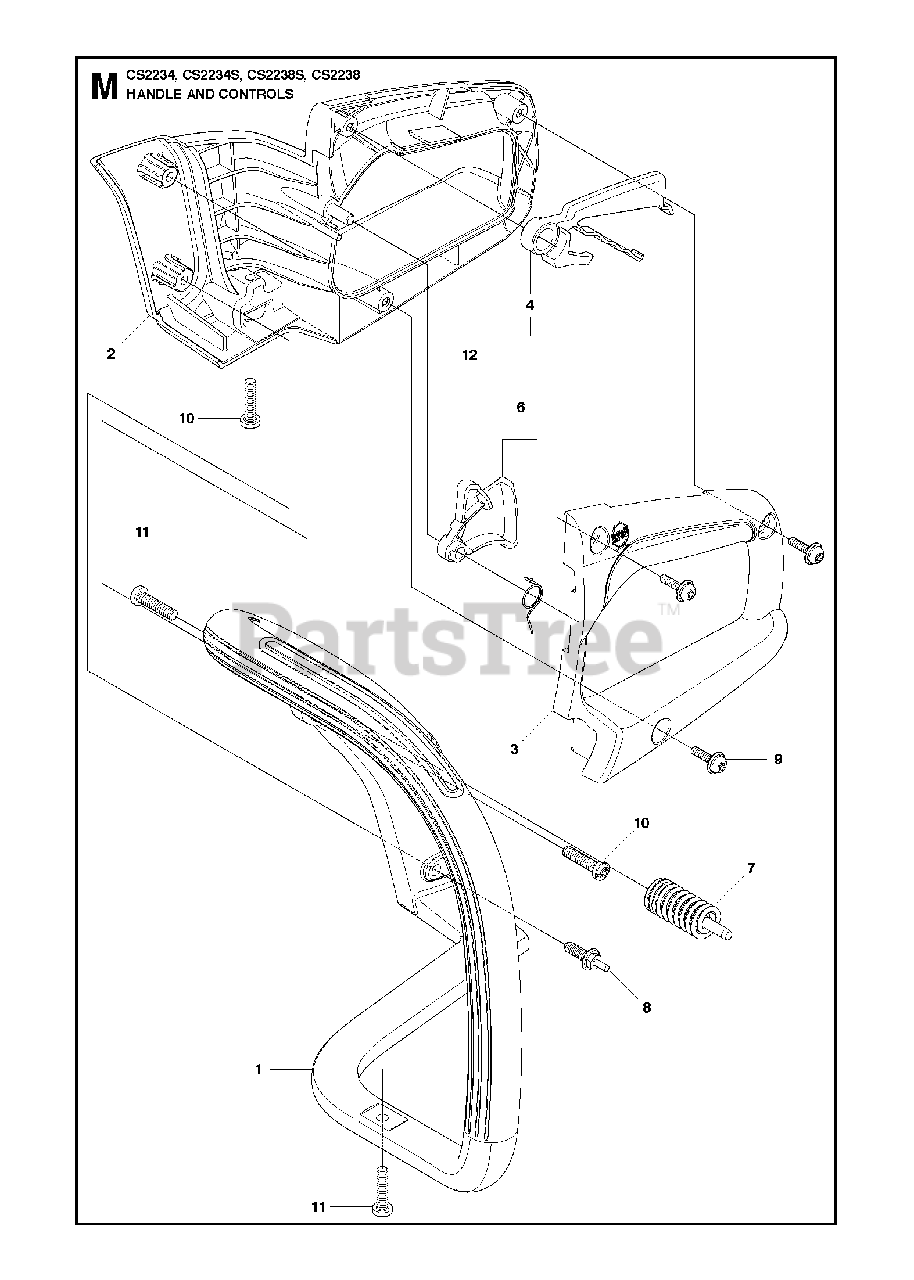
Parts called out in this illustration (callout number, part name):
1	HANDLE FRONT
2	HANDLE REAR
10	SCREW FILTER PLATE
11	SCREW M5.38-14X22.225MM
12	KIT TRIGGER LOCKOUT
